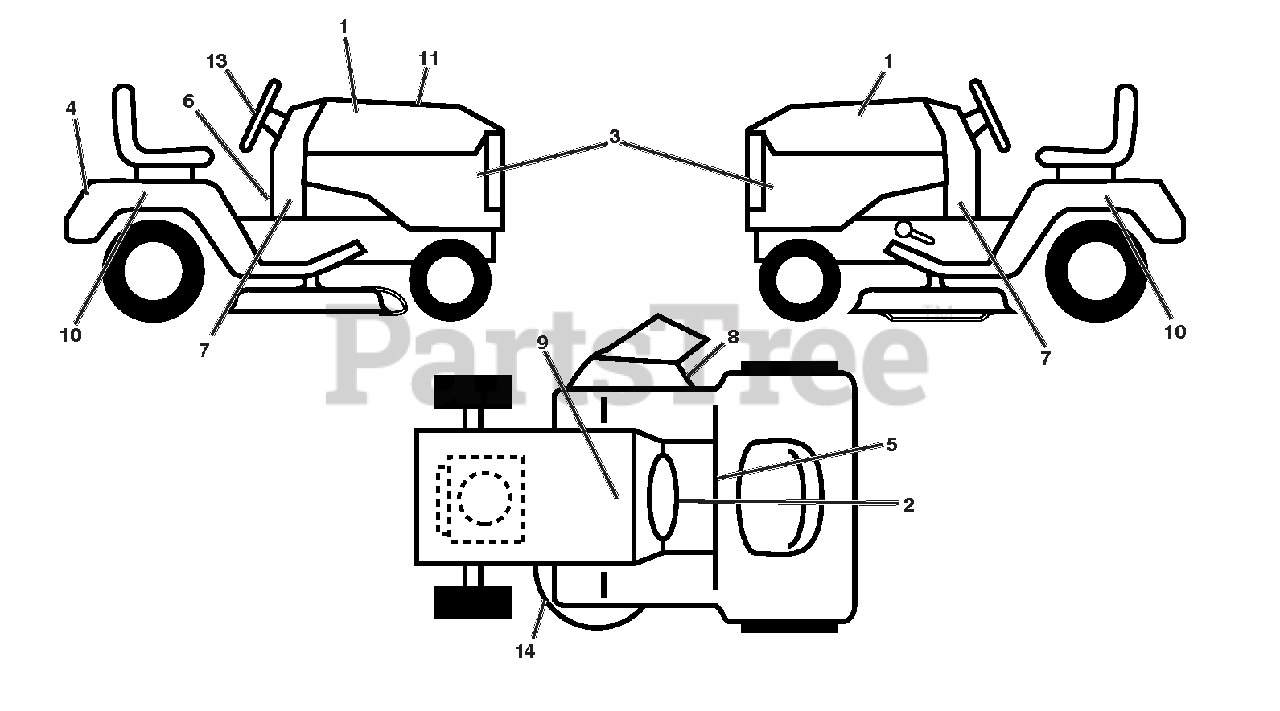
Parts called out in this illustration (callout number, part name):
1	DECAL.HOOD.LH/RH.
2	DECAL, WARNING START INST.
3	DECAL.SDPNL.PWRDBY KOHL.ARIENS
4	DECAL.FENDER.REAR.ARIENS
5	DECAL.FENDER
6	Decal, Spark Arrester
7	DECAL DASH LOWER
8	DECAL.MOWER.WARN.KEEP HAND AWY
9	DECAL.BAT.DAN/POI P/L SYM.WPN
10	DECAL, FENDER
11	DECAL. REPLACEMENT
13	DECAL.WHEEL.STEER.ARIENS
14	DECAL.V-BELT.SCH.42/46"MEC/ELE
